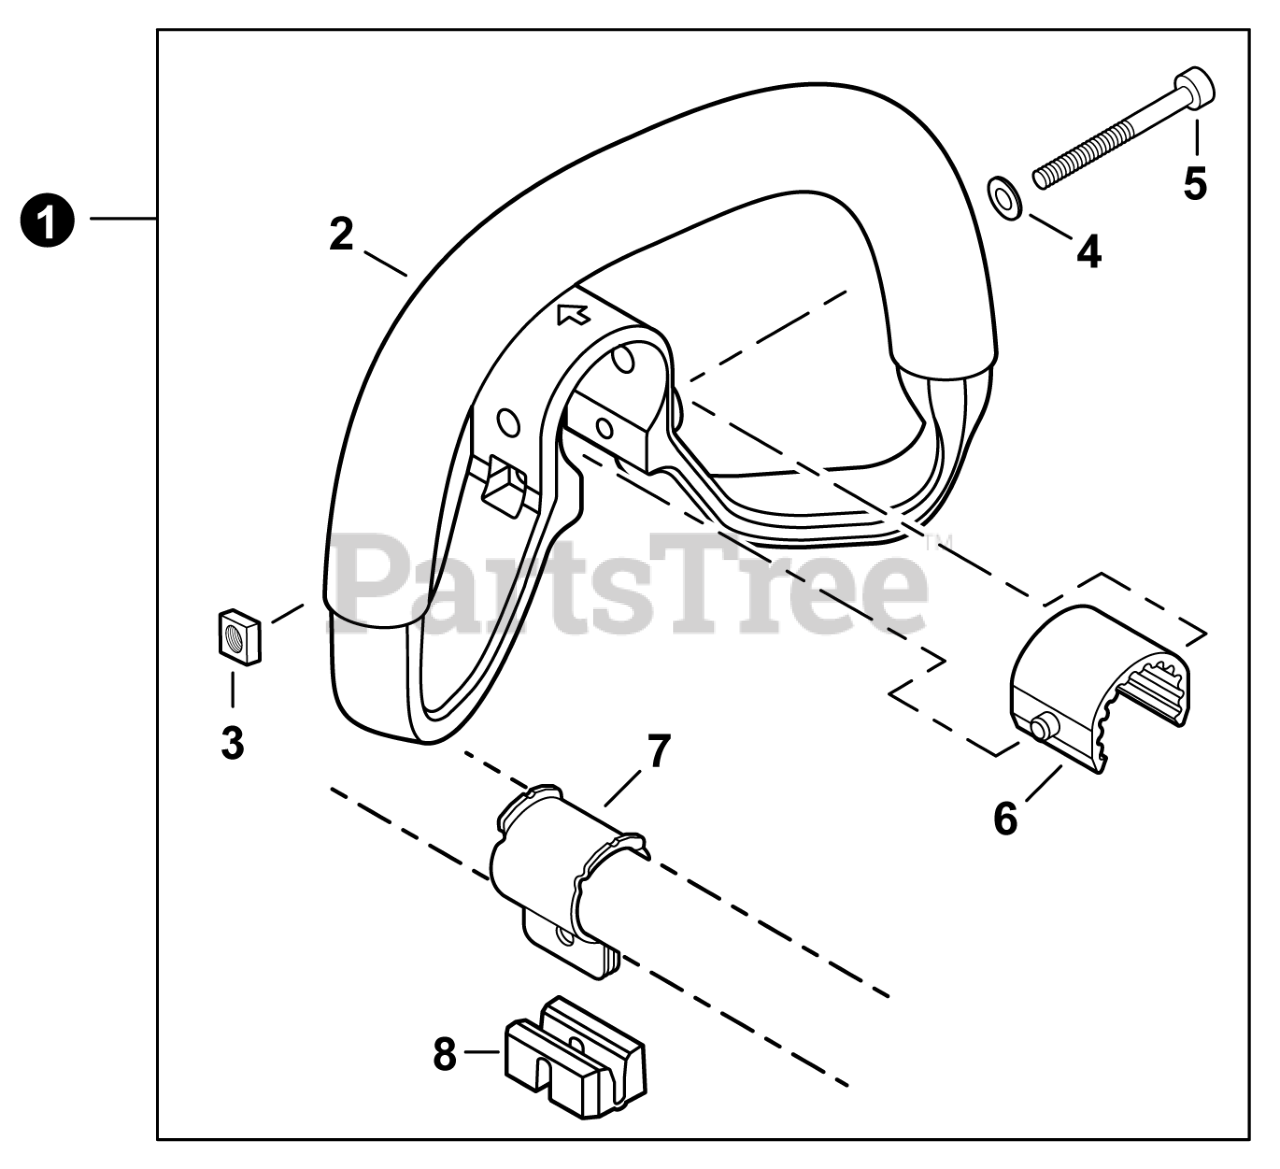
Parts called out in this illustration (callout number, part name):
1	HANDLE ASSY - SUPPORT
2	HANDLE, SUPPORT
4	WASHER 5.5x12x0.8
5	BOLT, TORX 5x45
6	CUSHION
7	BRACKET, MOUNTING
